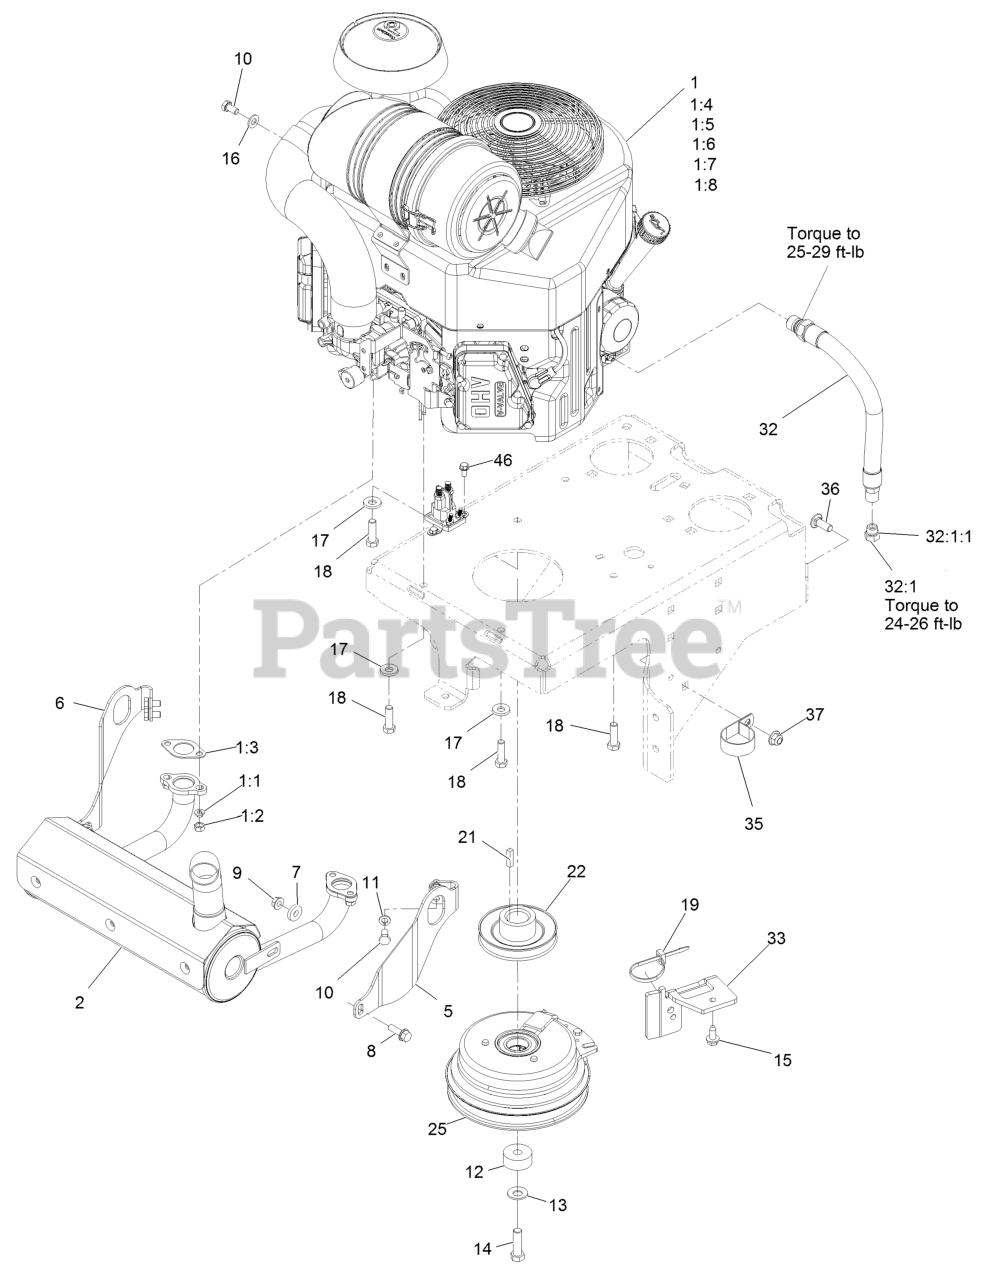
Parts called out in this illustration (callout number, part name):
1:1	WASHER-LOCK
1:3	GASKET-EXHAUST
1:4	FILTER-OIL
1:6	ELEMENT-FILTER, AIR (OUTE
1:7	ELEMENT-FILTER, AIR (INNE
2	MUFFLER, KAWASAKI, 22-26
5	BRACKET-MUFFLER MOUNT, LH
6	BRACKET-MUFFLER MOUNT, RH
8	SCREW-HHF
10	SCREW-HH
11	WASHER-LOCK
12	KEEPER-CLUTCH
13	WASHER-SPRING
14	SCREW-HH
15	Screw-HWH 5/16-18 X 3/4 Tf
16	WASHER-PLAIN
17	WASHER-BELLEVILLE
18	SCREW-HH
19	TIE-CABLE
25	CLUTCH-200 FT-LB, 1.125 B
32	ENGINE OIL DRAIN HOSE ASM
32:1	PLUG-HH
32:1:1	O-RING
33	BRACKET-ANCHOR, CLUTCH
35	CLAMP-R
36	SCREW-CARR
37	NUT-HF, NI
46	SCREW-HWH
